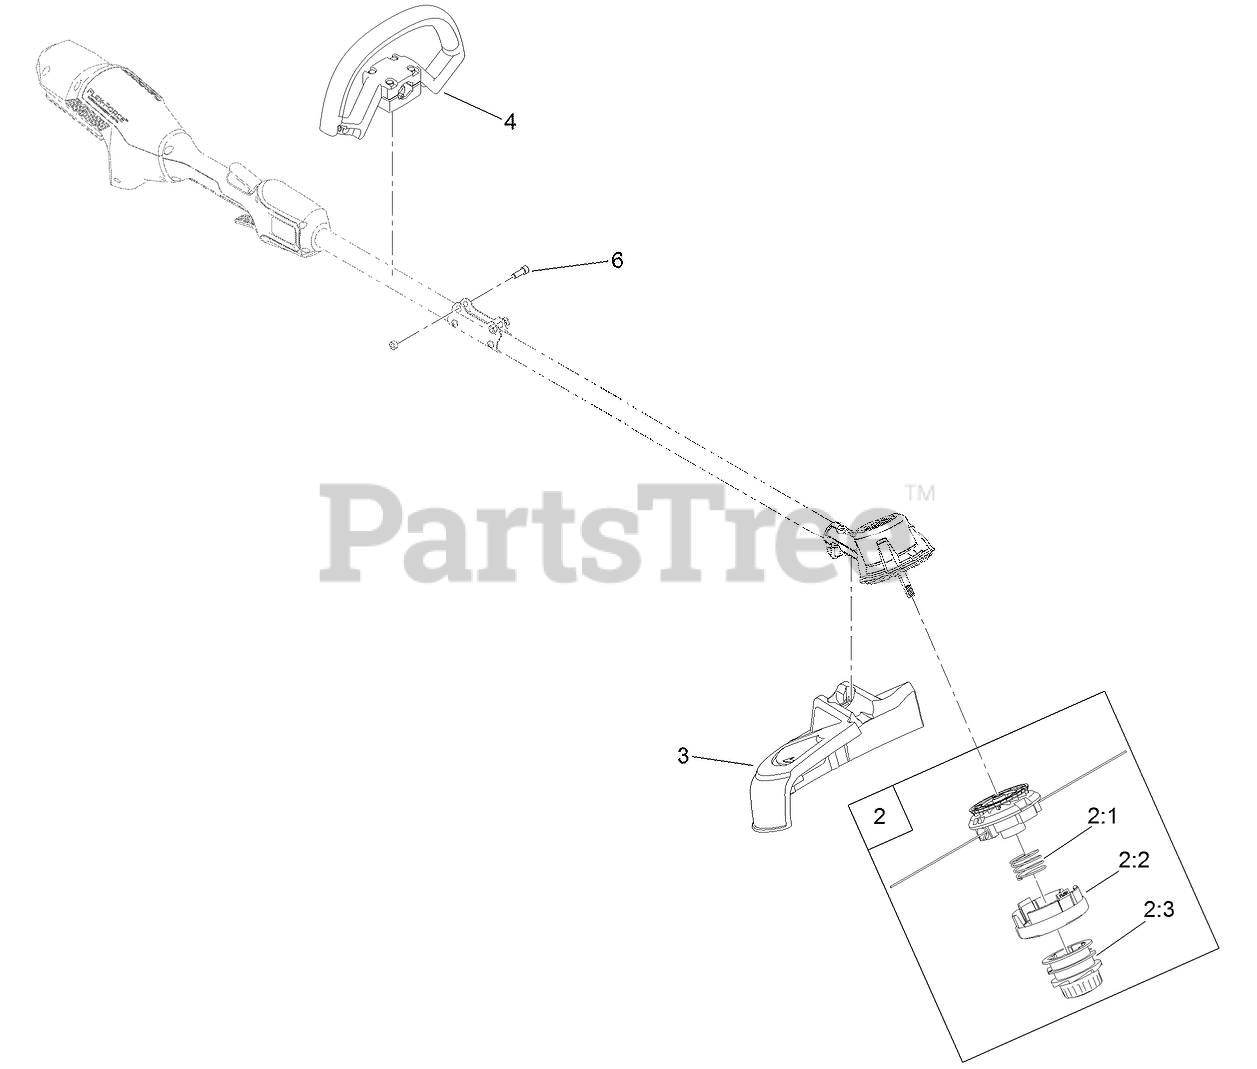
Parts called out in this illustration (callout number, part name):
2	BUMP FEED HEAD ASM
2:1	SPRING-SPOOL
2:2	CAP-FEED, BUMP
3	SHIELD-GRASS
4	HANDLE-TRIMMER
6	SCREW-HSH
